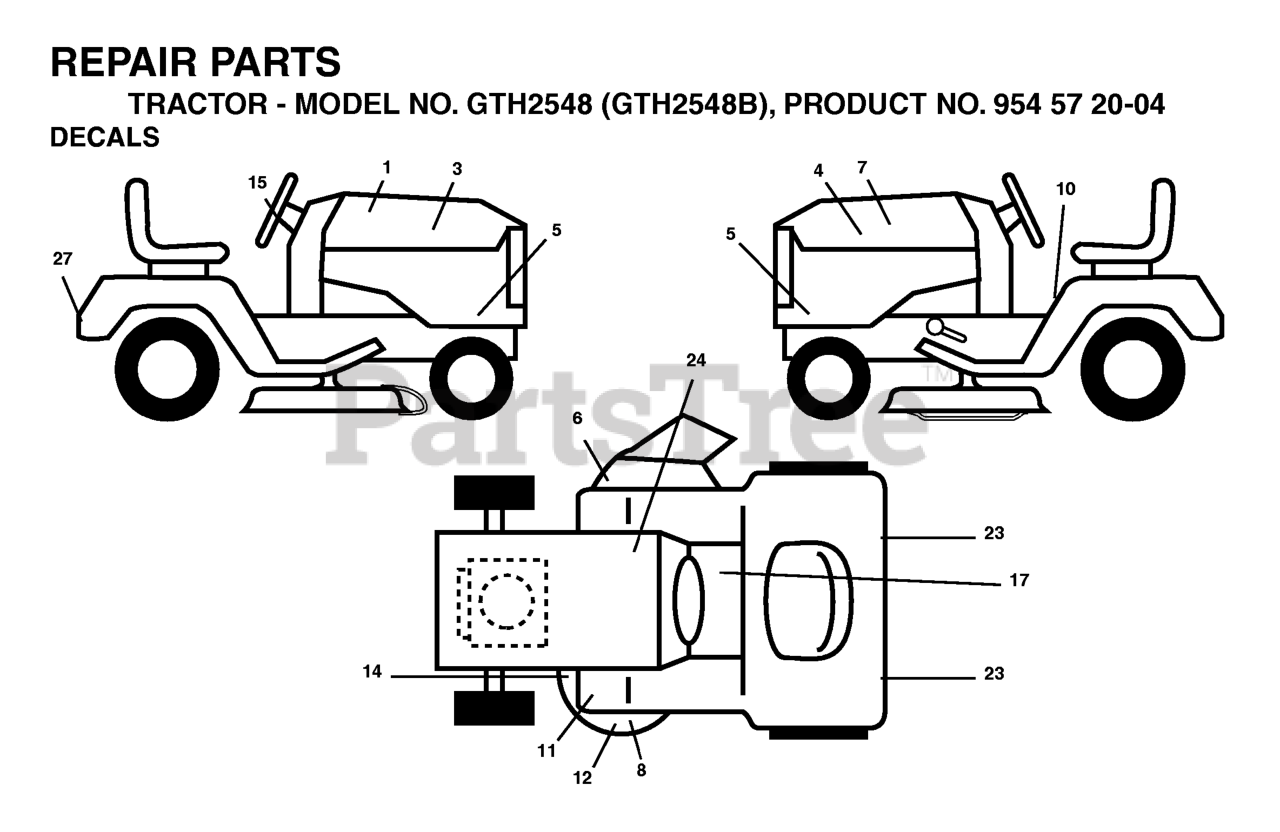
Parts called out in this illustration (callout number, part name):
1	DECAL.RPL.GTH2548
6	DECAL.WARN.KEEP.HAND.AWAY
7	DECAL HOOD CUST. RESP.
8	DECAL, MOWER HEAVY DUTY
10	DECAL FENDER DANGER
11	DECAL, FOOTREST
12	DECAL CLUTCH/BRAKE
14	DECAL V-BELT SCHEMATIC
15	DECAL.STEERING.HUSQ.BLUE
17	DECAL, SADDLE BRAKE PARKING
23	REFLECTOR-TAIL YT
24	DECAL BTRY SYMBOLS
27	DECAL.BYPASS.FENDER.CRD.LT.YT
